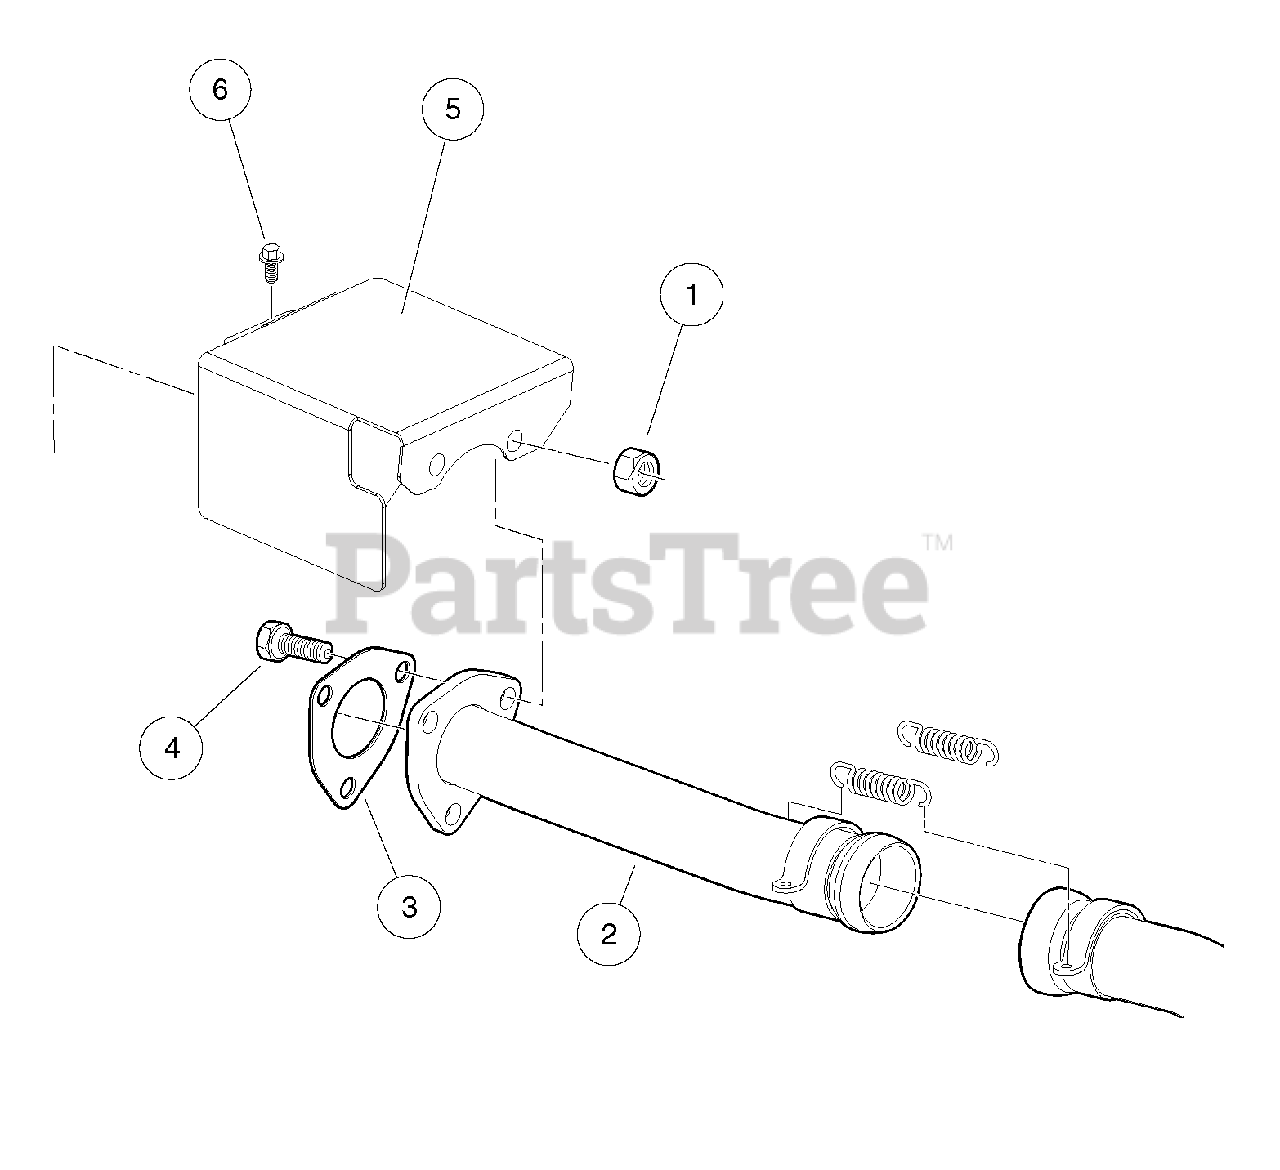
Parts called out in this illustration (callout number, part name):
1	Nut,m8,all Metal Lock
2	Pipe, Exhaust Diesel Main
3	Gasket, Exhaust Diesel
4	Bolt, M8 X 1.25 X 40 with Loctite
5	Shield, Diesel Exhaust
6	Bolt, D722, Exhst Manfld Cover
